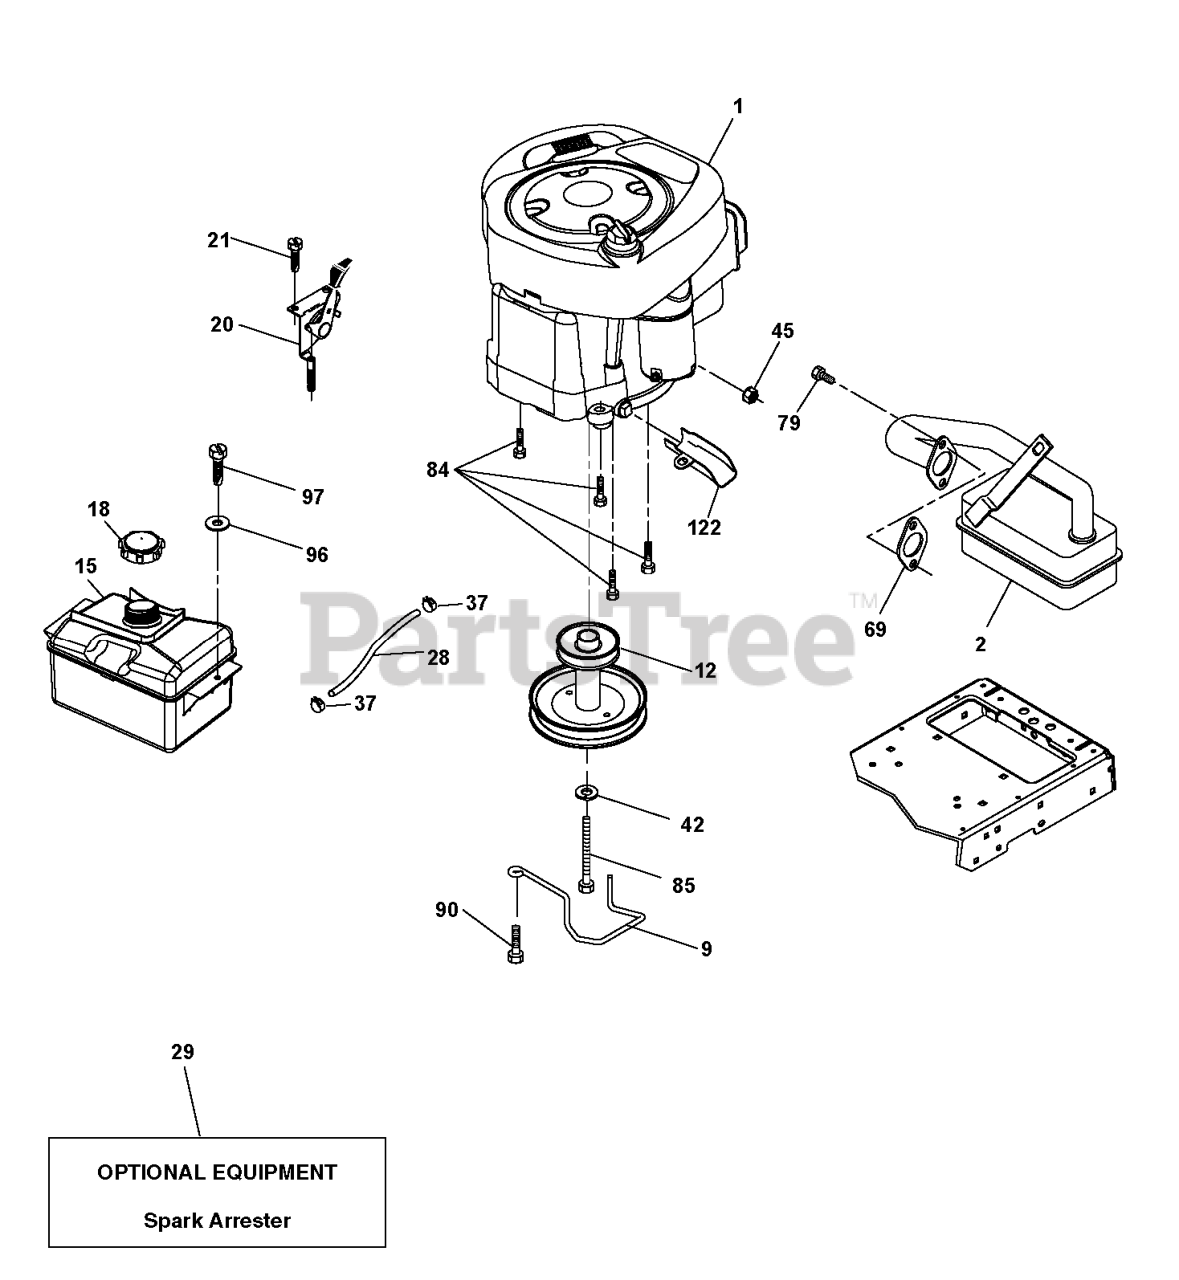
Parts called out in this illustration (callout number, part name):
2	MUFFLER.B&S.MODEL.21.11HP.OHV
9	KEEPER.BELT.ENGINE.3.25 (3 2)
12	PULLEY.ENG.CL.MECH.SLVR.LT/YT
15	RP TANK FUEL FRT 1.5 GAL
18	CAP ASM.FUEL.2.25"FR.
20	CONTROL.TH/CK.C.
21	SCREW.#10 X 0.750.BOS
28	LINE.FUEL.20
29	KIT.SPARK ARRESTOR 794945 B&S
37	HOSE CLAMP
42	LOCKWASHER
45	NUT
69	REPL BY 532 27 22-93
79	SCREW.SOCKET HD.5/16-1
84	SCREW.3/8-16
85	BOLT HEX 7/16-20X4-1/4"
90	SCREW 3/8-16X1
97	SCREW HEXWSHR 1/4-20X3/4
122	EXTENSION DRAIN OIL
